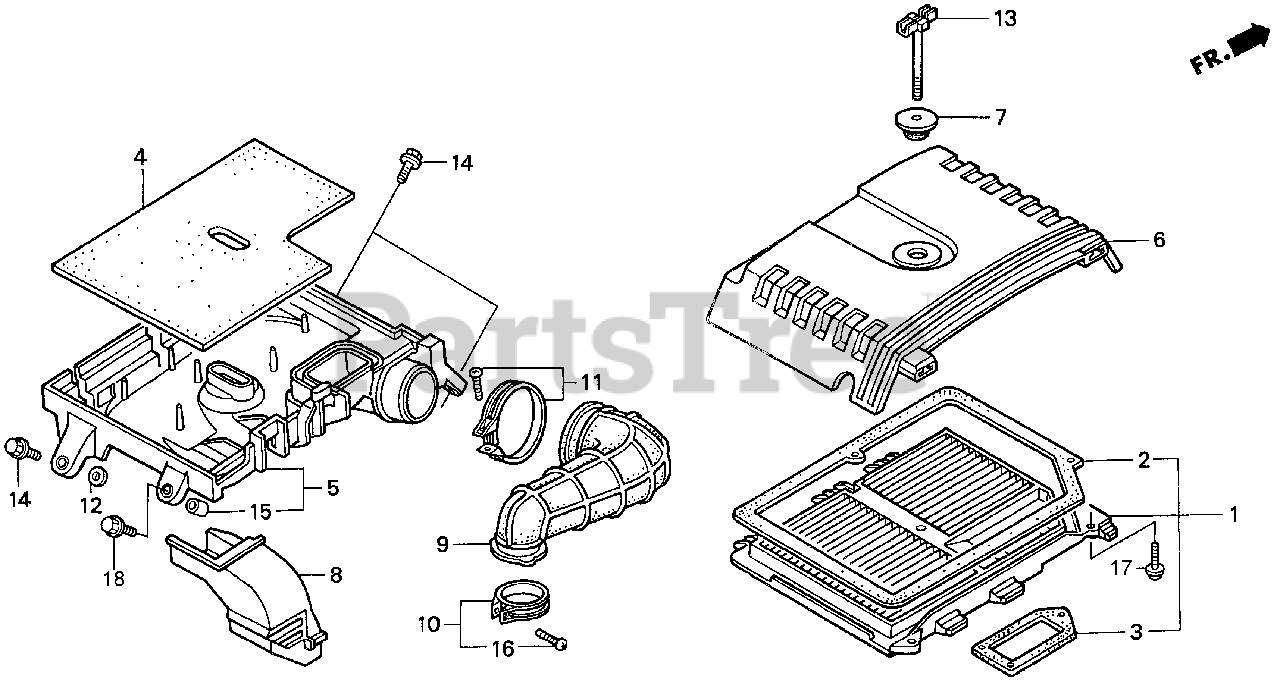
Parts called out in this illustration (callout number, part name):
1	ELEMENT SET, AIR CLEANER
2	GASKET A, ELEMENT
3	GASKET B, ELEMENT
4	FILTER (OUTER)
5	HOUSING, AIR CLEANER
6	COVER, AIR CLEANER
7	GROMMET, AIR CLEANER
8	HOSE, AIR CLEANER
9	TUBE, AIR CLEANER CONNECTING
10	BAND, AIR CLEANER CONNECTING TUBE
11	BAND, AIR CLEANER CONNECTING TUBE (50)
13	BOLT, AIR CLEANER
14	BOLT, FLANGE (6X23)
15	COLLAR, AIR CLEANER HOUSING
16	SCREW, PAN (4X20)
17	SCREW-WASHER (5X16)
18	BOLT, FLANGE (6X18)
